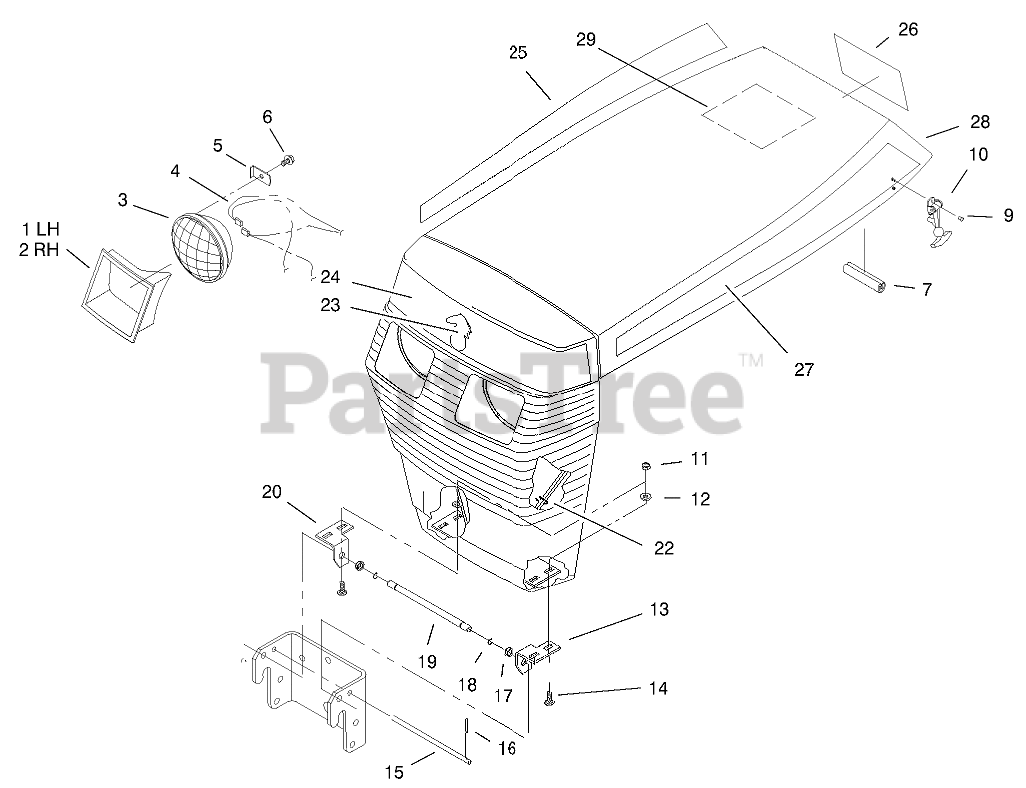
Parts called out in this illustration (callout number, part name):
1	BEZEL-HEADLIGHT, LH
2	BEZEL-HEADLIGHT, RH
3	HEADLAMP
4	HARNESS-HEADLIGHT
5	LOCK-HEADLIGHT
6	SCREW-HWH
7	EDGING-CONSOLE
9	RIVET-POP
10	HANDLE ASM
11	NUT-LOCK, NI
12	WASHER-FLAT
13	BRACKET-GRILL, LH
14	SCREW-CARR
15	ROD-HOOD STOP
16	PIN-COTTER
17	BUSHING-NYLINER
18	RING-RETAINING
19	ROD-GRILL PIVOT
20	BRACKET-GRILL, R H
22	TIE-CABLE
23	LOGO - HORSEHEAD
24	DECAL-FRONT HOOD, TOP
25	DECAL - RH HOOD TOP
26	DECAL-DANGER, HOOD
27	DECAL - LH HOOD TOP
28	Hood
29	DECAL-MAINTENANCE
